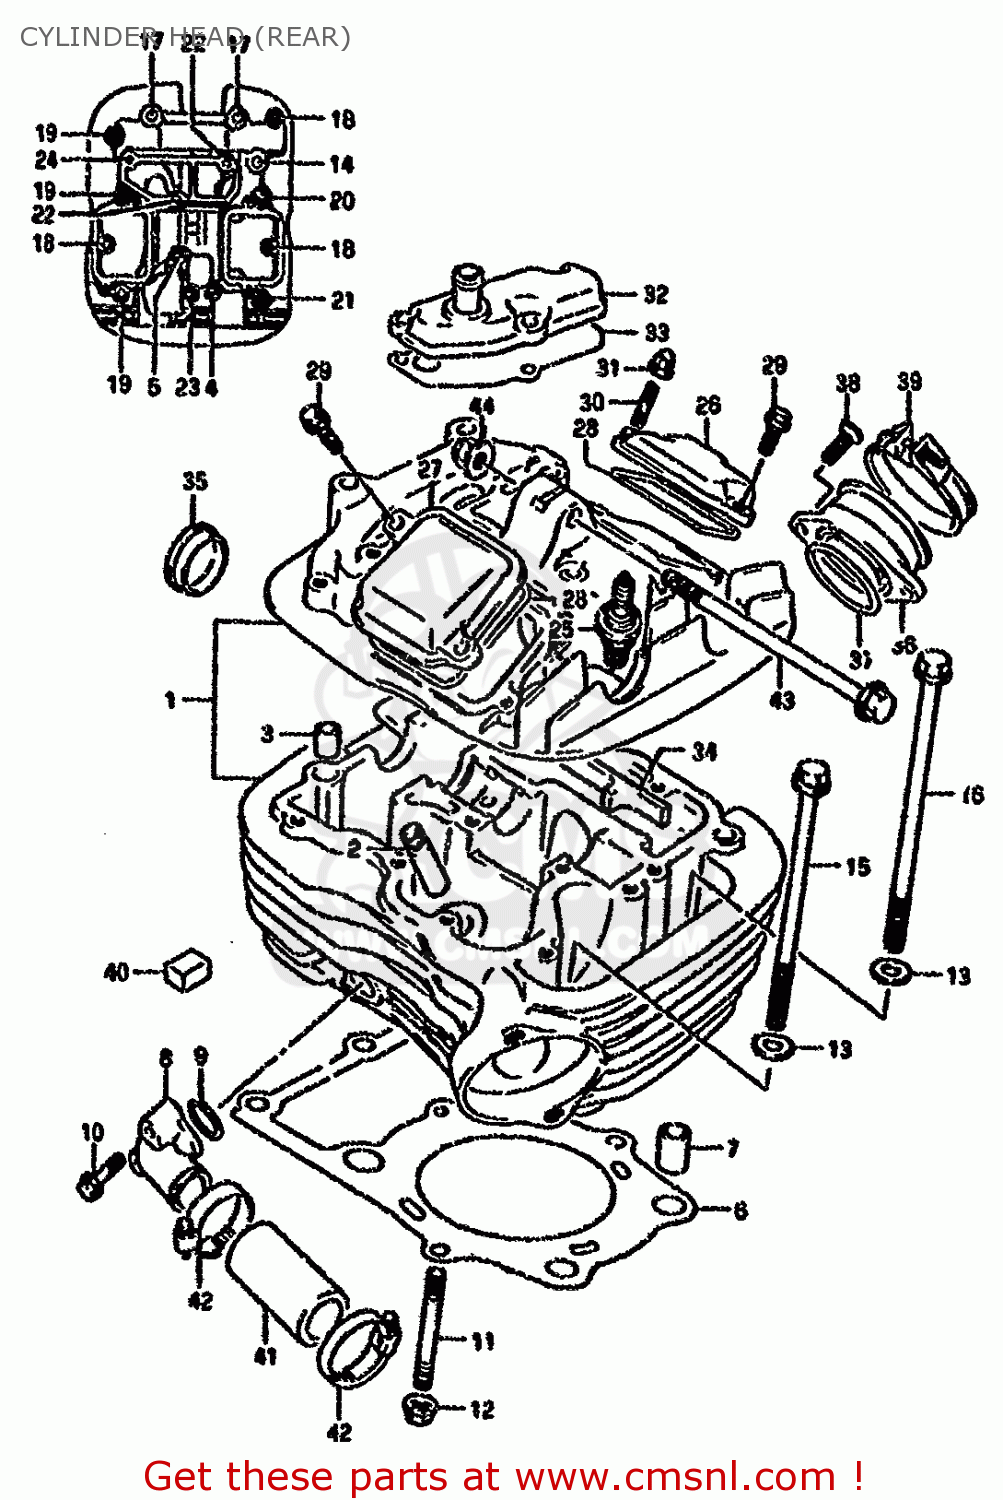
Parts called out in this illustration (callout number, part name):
1	HEAD ASSY,CYLINDER REAR
2	GUIDE,VALVE
3	PIN(11X14)
4	BOLT(6X50)
5	BOLT(6X55)
6	GASKET,CYLINDER HEAD RR (NAS)
7	PIN
8	UNION,CYLINDER HEAD WATER
9	O RING(D:2.4,ID:17.8)
10	BOLT
11	BOLT,STUD
12	NUT
13	WASHER(10.5X22X2.3)
14	BOLT(8X140)
15	BOLT(10X155)
16	BOLT(10X165)
17	BOLT 8X235
18	BOLT
19	BOLT
20	BOLT
21	BOLT
22	BOLT(6X55)
23	BOLT(6X50)
24	BOLT
25	PLUG,SPARK(DPR8EA-9)
26	CAP,INSP.INT
27	CAP,INSPECTION,EXHAUST
28	GASKET,INSPECTION CAP (NAS)
29	BOLT
30	STUD 6X16
31	NUT
32	COVER,BREATHER
33	GASKET,BREATHER COVER (NAS)
34	PLATE,HEAD COVER RR
35	PLUG(OD:30)
36	PIPE COMP,INTAKE,REAR
37	O-RING (D:2.4 ID:39.7)
38	SCREW
39	CLAMP
40	PAD
41	HOSE,CYLINDER HEAD JOINT
42	CLAMP
43	BOLT(8X135)
44	NUT
